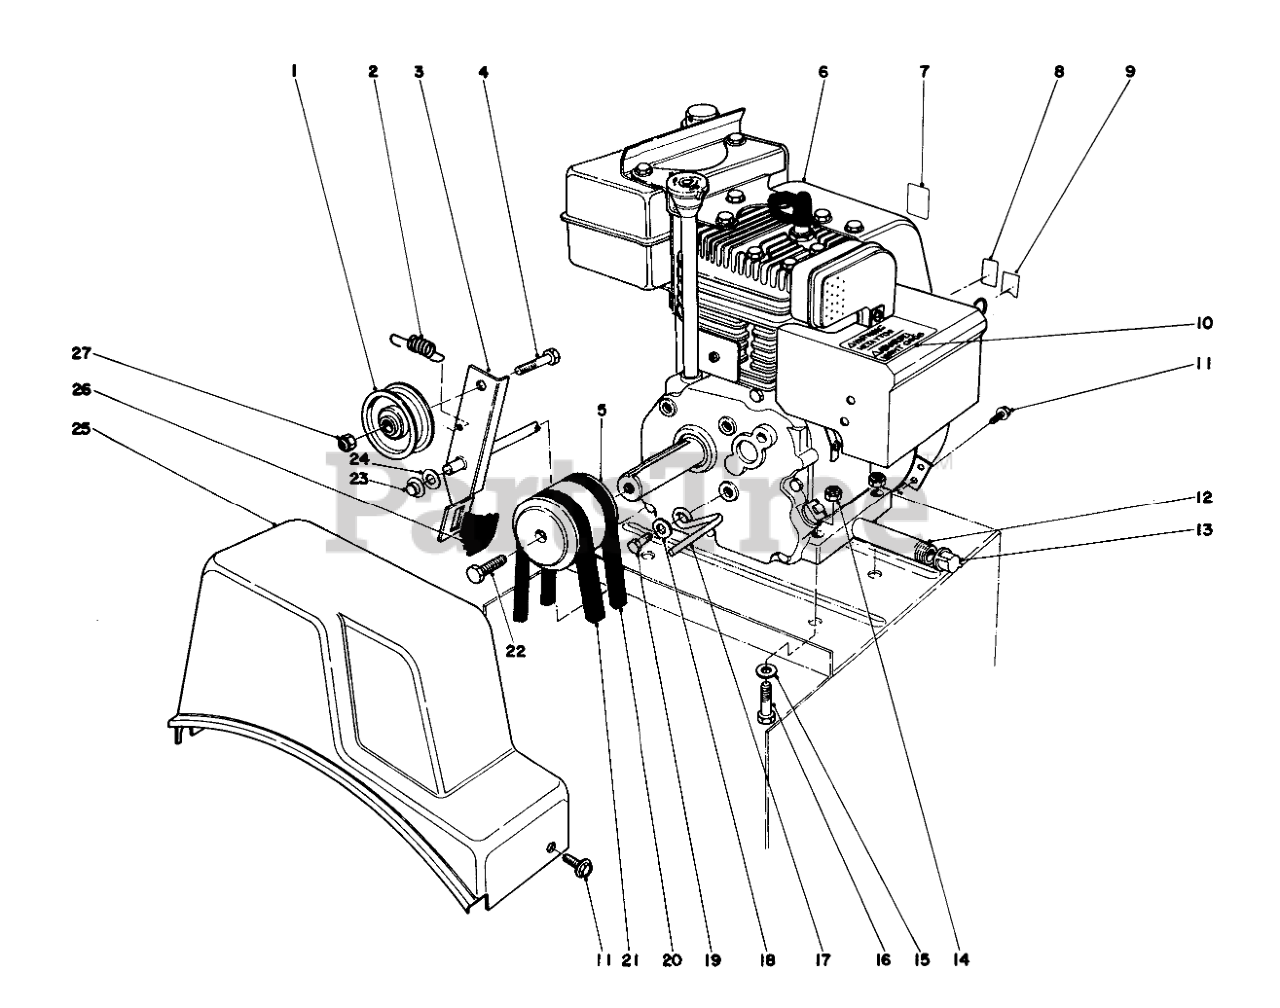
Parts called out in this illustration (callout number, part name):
1	PULLEY-IDLER
2	EXTENSION SPRING
3	Auger Clutch (Incl. Ref. #26)
4	SCREW-HH
5	Engine Pulley
6	Engine
7	PRIMER DECAL
8	DECAL THROTTLE
9	CHOKE DECAL
10	Decal Hot Surface Warning
11	SCREW
12	PIPE NIPPLE
13	CAP-PIPE
14	NUT-LOCK, NI
15	WASHER-PLAIN
16	SCREW-HH
17	RETAINER-BELT
18	WASHER-LOCK
19	SCREW-HH
20	V BELT-3L, TRACTION
21	V-BELT (29.50 INCH)
22	Screw-Special
23	RETAINER-PUSH ON
24	WASHER-FLAT
25	COVER-BELT
26	Brake Pad
27	NUT-LOCK, CONE
